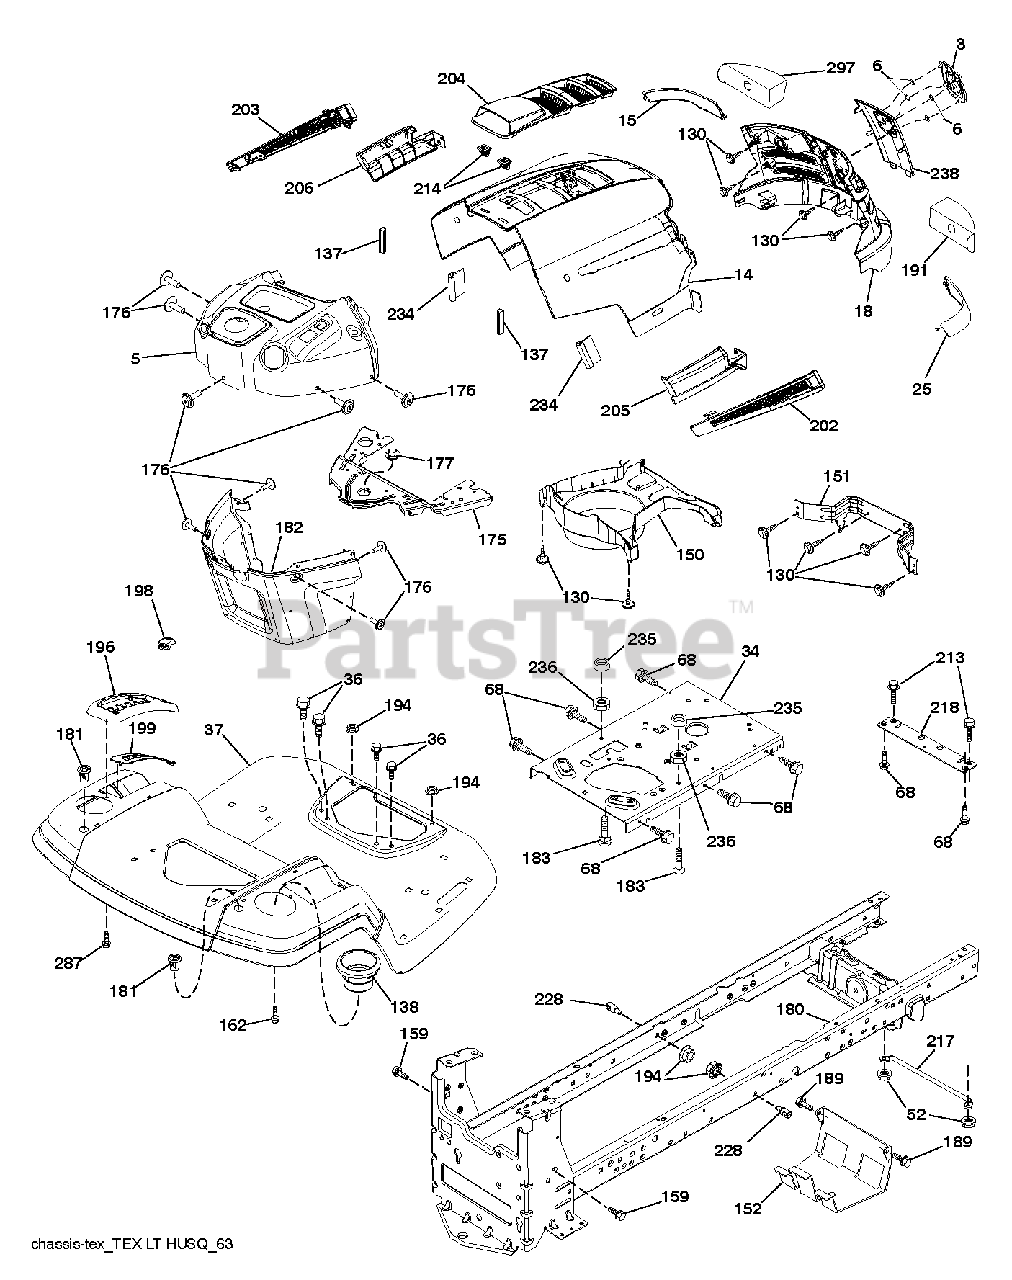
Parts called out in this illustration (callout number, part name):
3	LOGO.HUSQ.GT.LT.CROWN.H
5	SUBASM.DASH.UPPER.W/BUMPER
14	HOOD.HUSQVARNA.LT.ORANGE
15	LENS.HUSQVARNA LT.RH
18	GRILLE.SVC.HUSQVARNA.GREY
25	LENS.HUSQVARNA LT.RH
34	PLATE PLATE ENGINE
36	SCREW 5/16"
37	FENDER.TLT.FS.W/CUPHLD.ORANGE
52	LOCKNUT
68	SCREW LT
130	SCREW.#10 X 0.750.BOS
137	BUMPER DASH
138	HOLDER.CUP.LT.GREY
151	BRACKET PIVOT
152	SHIELD.BROWNING.W/TEX
159	SCREW, 3/8-16X3/4
162	SCREW.HI-LO.CONSOLE
175	CROSSMEMBER
176	SCREW.#10-24X5/8.RN.QU
177	BUSHING STEERING
180	CHASSIS
181	BUSHING.MNT.FEND.CRGO.TEX.49
182	DASH.LOWER.PREDATOR LT
183	BOLT.5/16-18X1-1/4 FULL.THREAD
189	SCREW
191	INSERT.REFLECTIVE.RH.
194	NUT LOCK HEX FLANGE 5/16-18
196	CONSOLE.DECK.LIFT.GREY
198	INDICATOR.DECK.LIFT.RED
199	PLATE.DECK.LIFT.HUSQ.LT
202	VENT.SIDE.HUSQVARNA.LT.RT
203	VENT.SIDE.HUSQVARNA.LT.LFT
204	SUBASM.TOP.VENT.HUSQ.LT
205	SKIRT.SIDE.HUSQVARNA.LT.RT
206	SKIRT.SIDE.HUSQVARNA.LT.LEFT
213	BOLT
214	CLIP.RETAINER.TINNER.
217	ROD.PIVOT.HOOD
218	X-PIECE.HOOD.STOP.NON/
228	STUD.FASTNER.W/ANTI-ROTATE
234	BUMPER.HOOD.TEX.HUSQVARNA
235	SPACER FENDER
236	NUT.CENTERLOCK.5/16-
238	TRIM.HUSQ LT.668
287	SCREW 1/4X20
297	INSERT REFLECTIVE
